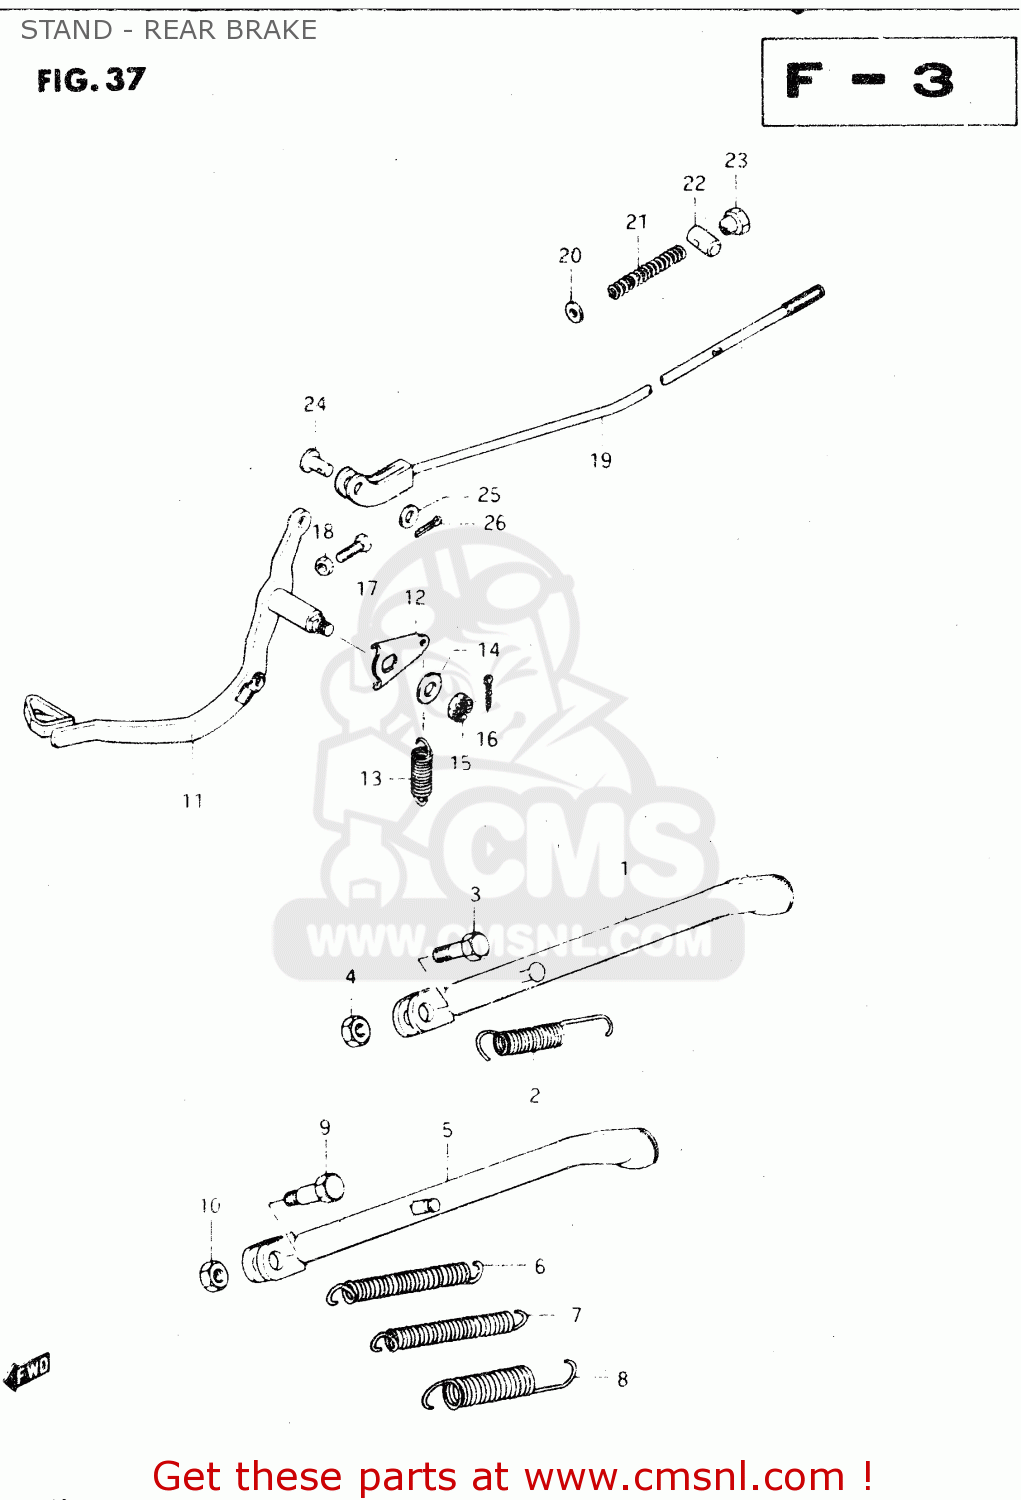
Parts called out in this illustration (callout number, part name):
1	STAND,SIDE
2	SPRING
3	BOLT(10X30)
4	NUT
5	STAND PROP
6	SPRING
7	SPRING
8	SPRING, OUTER
9	BOLT
10	NUT
11	PEDAL,BRAKE
12	ARM,BRAKE RETURN SPRING
13	SPRING
14	WASHER
15	NUT 8MM
16	PIN 20X20
17	BOLT(6X23)
18	NUT
19	ROD ASSY REAR BRAKE
20	WASHER
21	SPRING
22	PIN(11X18)
23	NUT
24	PIN
25	WASHER
26	PIN 20X20
